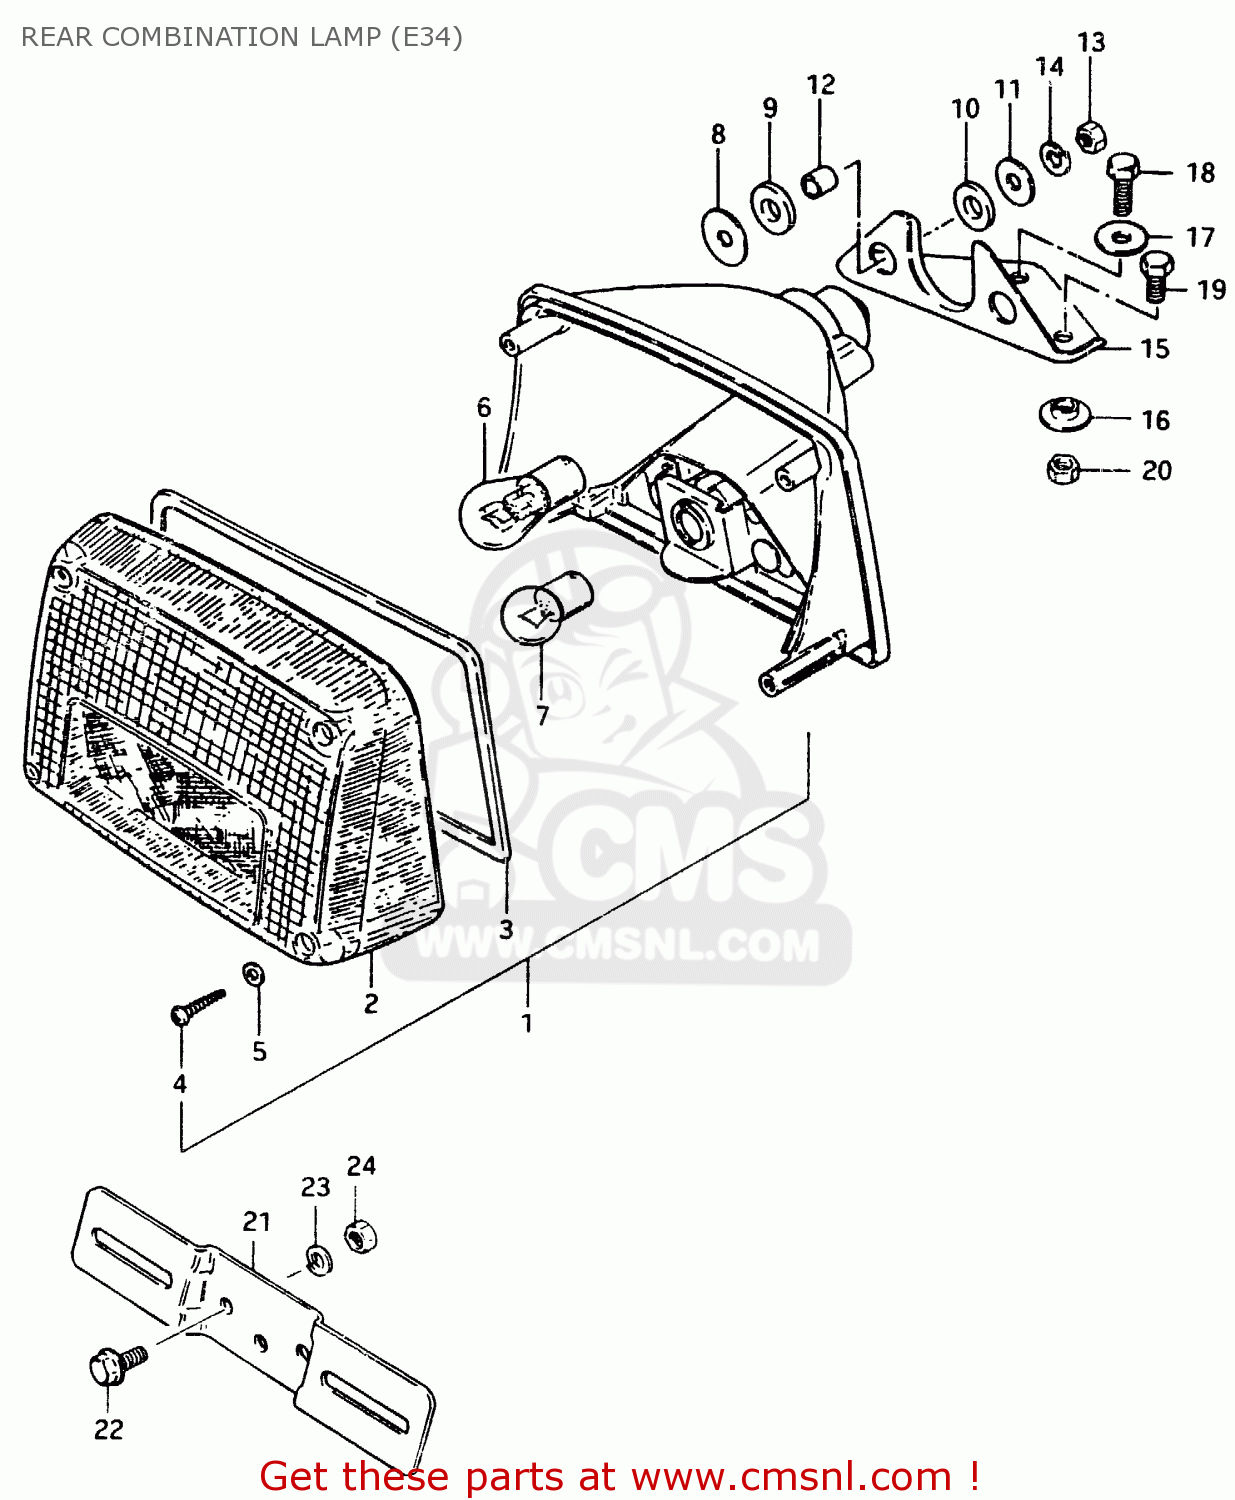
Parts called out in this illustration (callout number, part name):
1	LAMP, REAR COMBINATION
2	LENS
3	GASKET (NAS)
4	SCREW,REAR COMBINATION LAMP
5	GASKET (NAS)
6	BULB(12V21/5W)
7	BULB
8	WASHER
9	CUSHION
10	CUSHION
11	WASHER(6,5X22X1.6)
12	WASHER
13	NUT
14	LOCK WASHER
15	BRACKET,RR COMBINATION LAMP
16	WASHER
17	WASHER
18	BOLT
19	BOLT, UPPER
20	NUT 6MM
21	BRACKET, LICENSE PLATE
22	BOLT
23	LOCK WASHER
24	NUT
